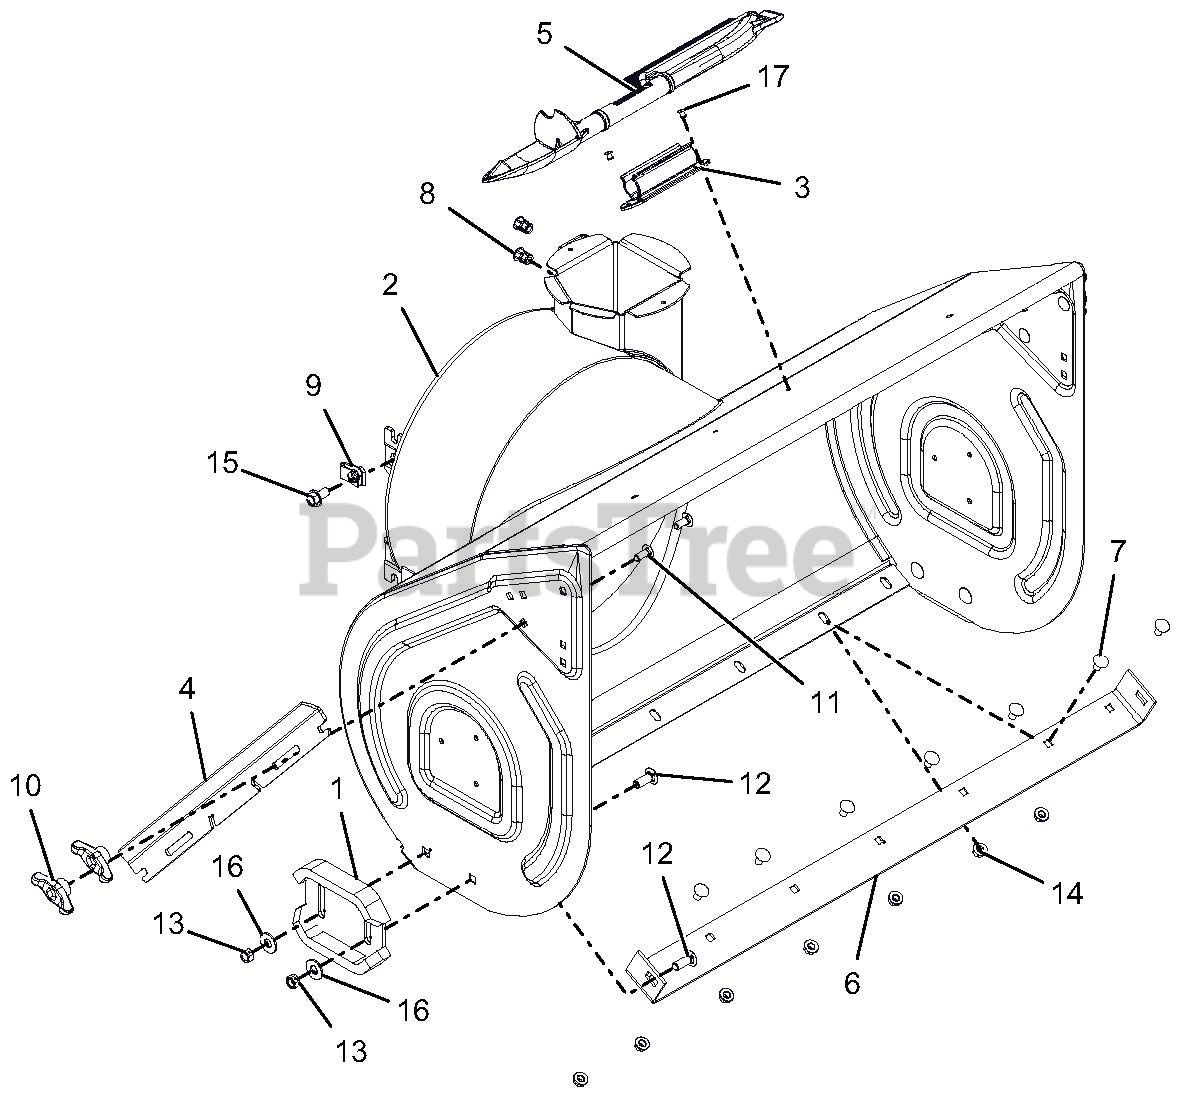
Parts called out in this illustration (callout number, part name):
1	RUNNER, SKID SHOE
2	BLOWER HOUSING W/DECAL 32"
3	MOUNT, SNOW CLEAN OUT
4	CUTTER, DRIFT
5	DEVICE, SNOW CLEAN OUT W/BRUSH
6	BLADE, SCRAPER-32"
7	BLT,RDSHHDSQSHNK .31-18X.62 YZ
8	NUT, THREADED INSERT .38-16
9	NUT-RTNR .375-16X.37
10	KNOB,WING .31-18 UNC NYL/TALC
11	@BLT-RHDSSQNK .31-18X.75 G5YZ
12	@BLT-RDHDSHSQNK.38-16X1.0 G5YZ
13	@NUT-LK-CTR .38-16 YWZC
14	@NUT-LK-TOP-FLG .31-18 YWZC
15	BLT-SERHFWH .38-16X.75 YWZC
16	@WSHR-FL-STL.438X1.00X.083 YWZ
17	RVT-POP .187 YZ
